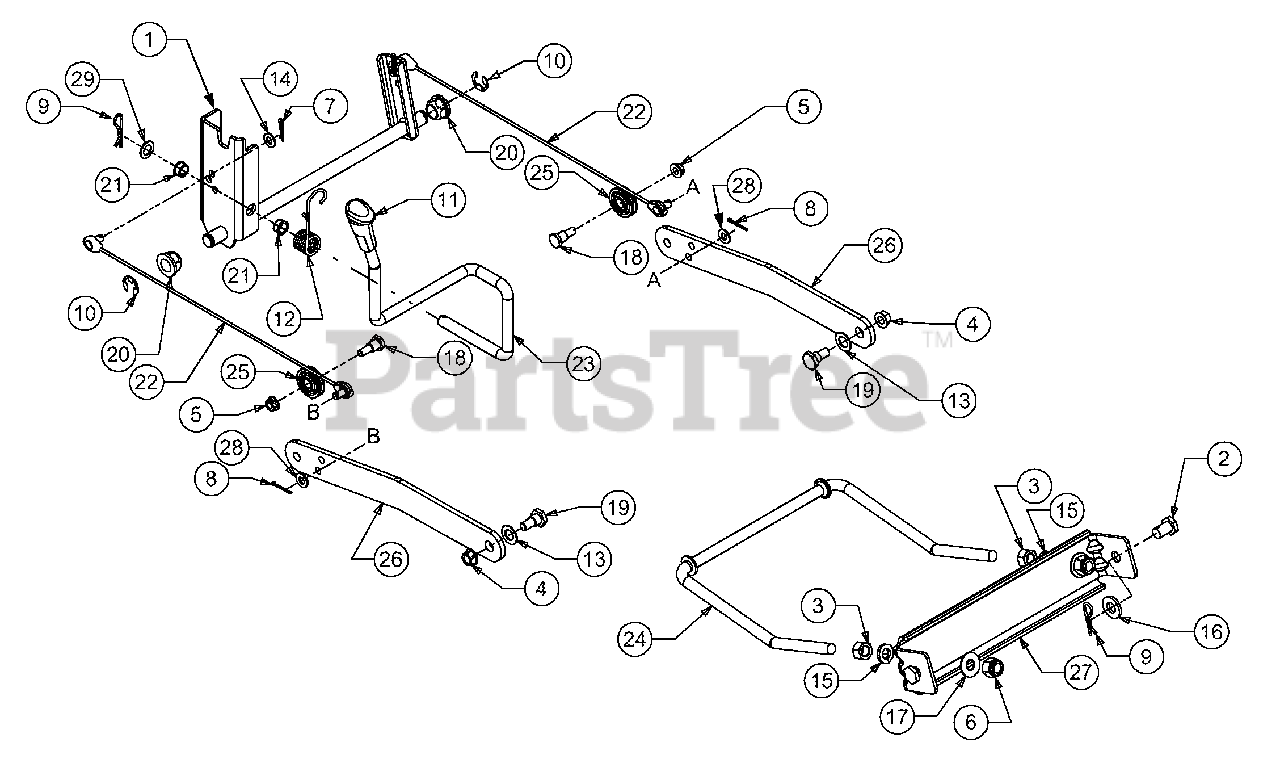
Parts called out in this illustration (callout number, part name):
2	Pin, Clevis, .50 Dia x .78 Lg
3	Nut, Hex, 1/2-13, Gr5
4	Nut, Flange Lock, 3/8-16
5	Nut, Flange Lock, 5/16-18, Gr5
6	Nut, Hex Lock, 1/2-13, Gr8, Nylon
7	Pin, Cotter, .072 Dia. x 1.13 Lg
8	Pin, Cotter, 3/32, 1.0
9	Pin, Click, .092 x 1.64 Lg
10	E-ring, .625 Dia. Shaft
11	Grip, Handle
12	Spring, Torsion
13	Washer, Flat, .53 x .93 x .050
14	Washer, Flat, .344 x .688 x .065
15	Washer, Lock, 1/2, Regular Duty
16	Washer, Flat, .531 x 1.062 x .134
17	Washer, Flat, .510 x 1.120 x .060
18	Screw, Hex Cap, 5/16-18x.620 Gr2
19	Shoulder Screw, 3/8-16
20	Bearing, Hex Flange
21	Bearing,Flange, Snap .500 ID
22	Cable, Lift, 16.16 Lg
23	Handle, Lift
24	Rod, Deck, Front Adjustment .5" Dia
25	Pulley, Roller
28	Washer, Flat, .344 x .62
29	Washer, Flat, .510 x .750 x .033
